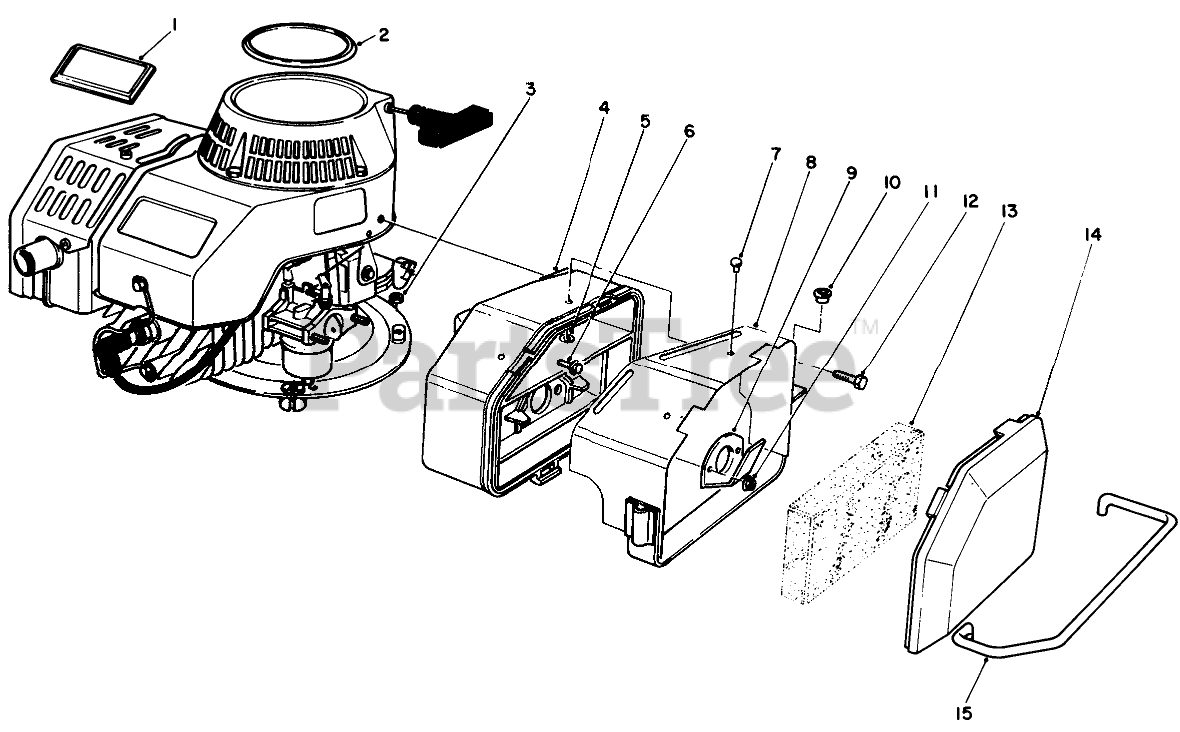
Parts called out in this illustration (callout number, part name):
1	Plate-Logo
2	Plate-Engine Logo
3	NUT-JAM
4	Air Cleaner Assembly (Incl. Ref. #5, 7 & 8)
5	WASHER-FLAT
6	HEX FL HD M.6X1.0X25MM
7	RIVET-POP
8	AIR CLEANER COVER WA
9	SPIT BACK DEFLECTOR
10	5/16 ID BSHG
11	NUT-LOCK
12	SCREW-HHF
13	FILTER
14	AIR CLEANER COVER
15	AIR CLEANER GUARD
